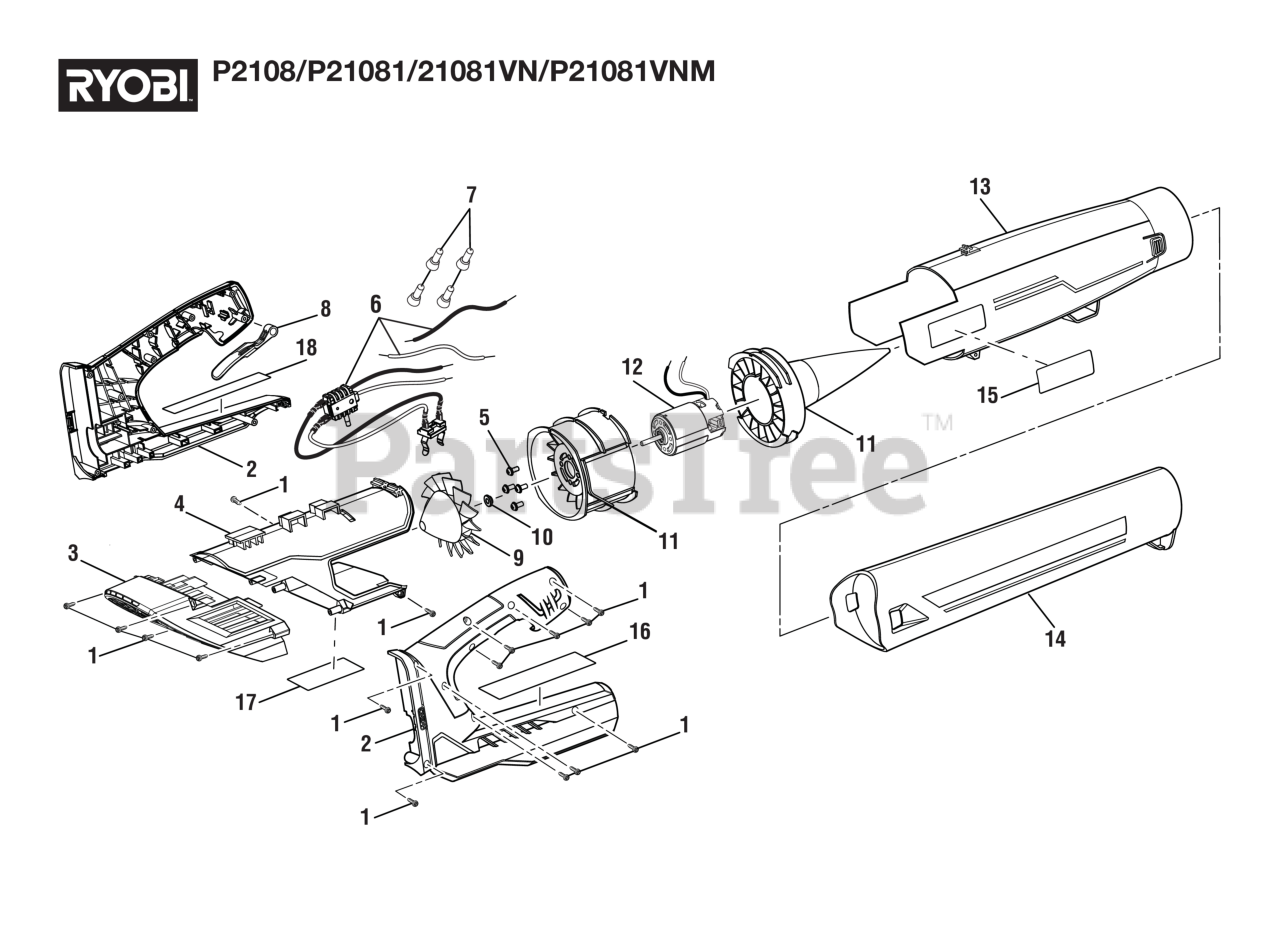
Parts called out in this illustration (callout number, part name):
1	Screw (M4 x 14 mm, T15 Torx Pan Hd.))
2	Handle Assembly
3	Inlet Guard
4	Inlet Housing Assembly
5	Screw w/Lock Washer (M5 x 8 mm, Pan Hd.)
6	Switch and Contact Plate Assembly
7	Wire Connector (Closed End)
8	Trigger Assembly (Variable Speed)
9	Fan Blade
11	Tail Cone Assembly
13	Blower Housing Outlet Assembly
14	Blower Tube
15	Logo Label (Ryobi)
16	Warning Label
17	Label, Data
18	Warning Icon Label
